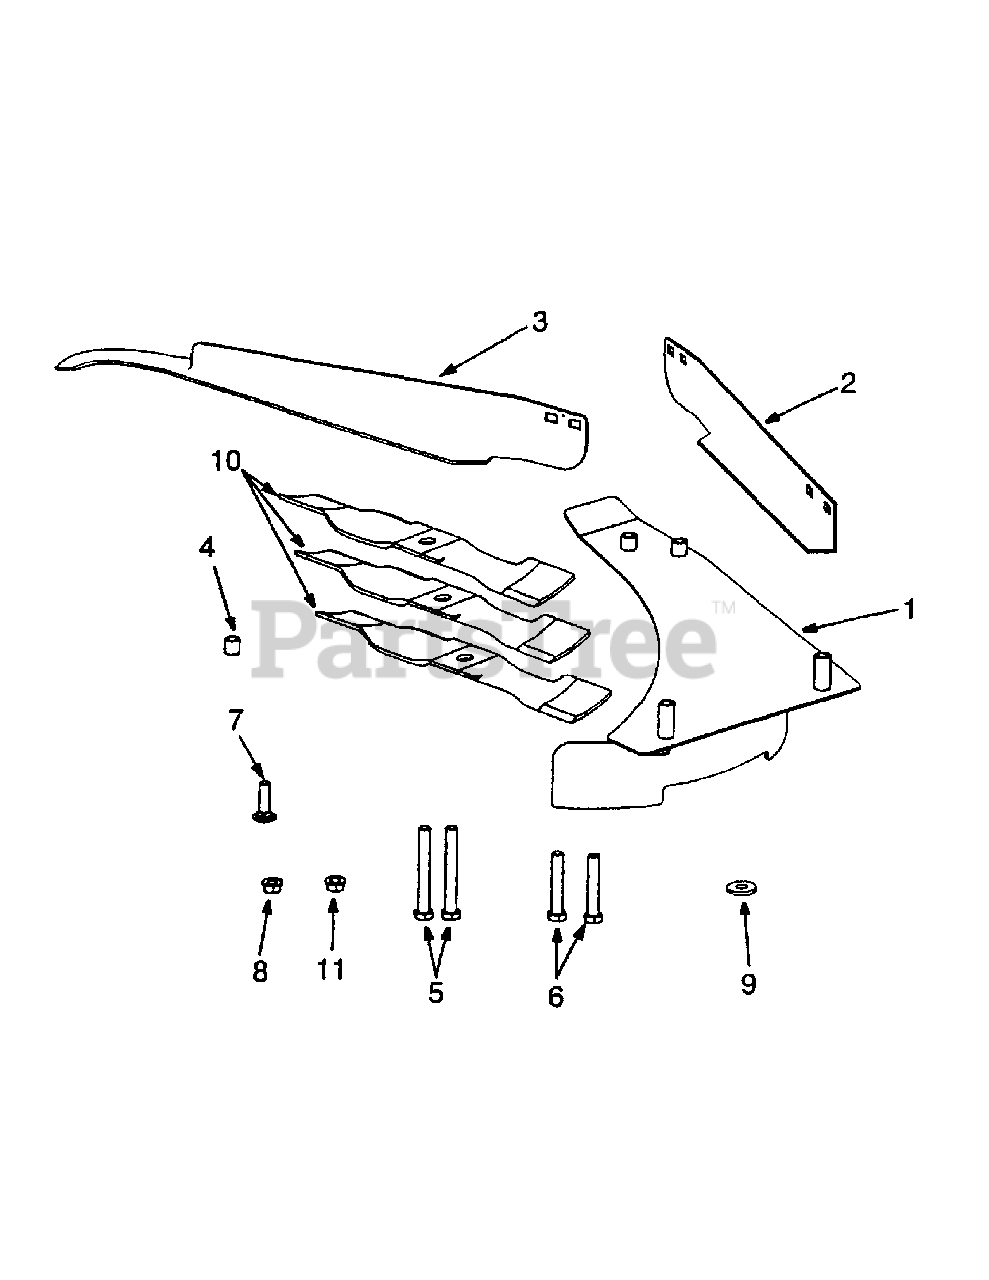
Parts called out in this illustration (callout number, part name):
1	Baffle Ass'y, 54" Mulching
2	Baffle, RH 54"
3	Baffle, LH 54"
4	Spacer, 39 ID x .63 OD x 1.1
5	Screw, Hex Cap, 3/8-16 x 2.75 GR5
6	Screw, Hex Cap, 3/8-16 x 1.75
7	Bolt, Carriage, 3/8-16 x .75 GR5
8	Nut, Hex 3/8-16
9	Washer, Lock, 1/2 Zinc
10	Blade, Mulching, 18.5 Lg
11	Nut, Hex Flange Lock, 3/8-16
